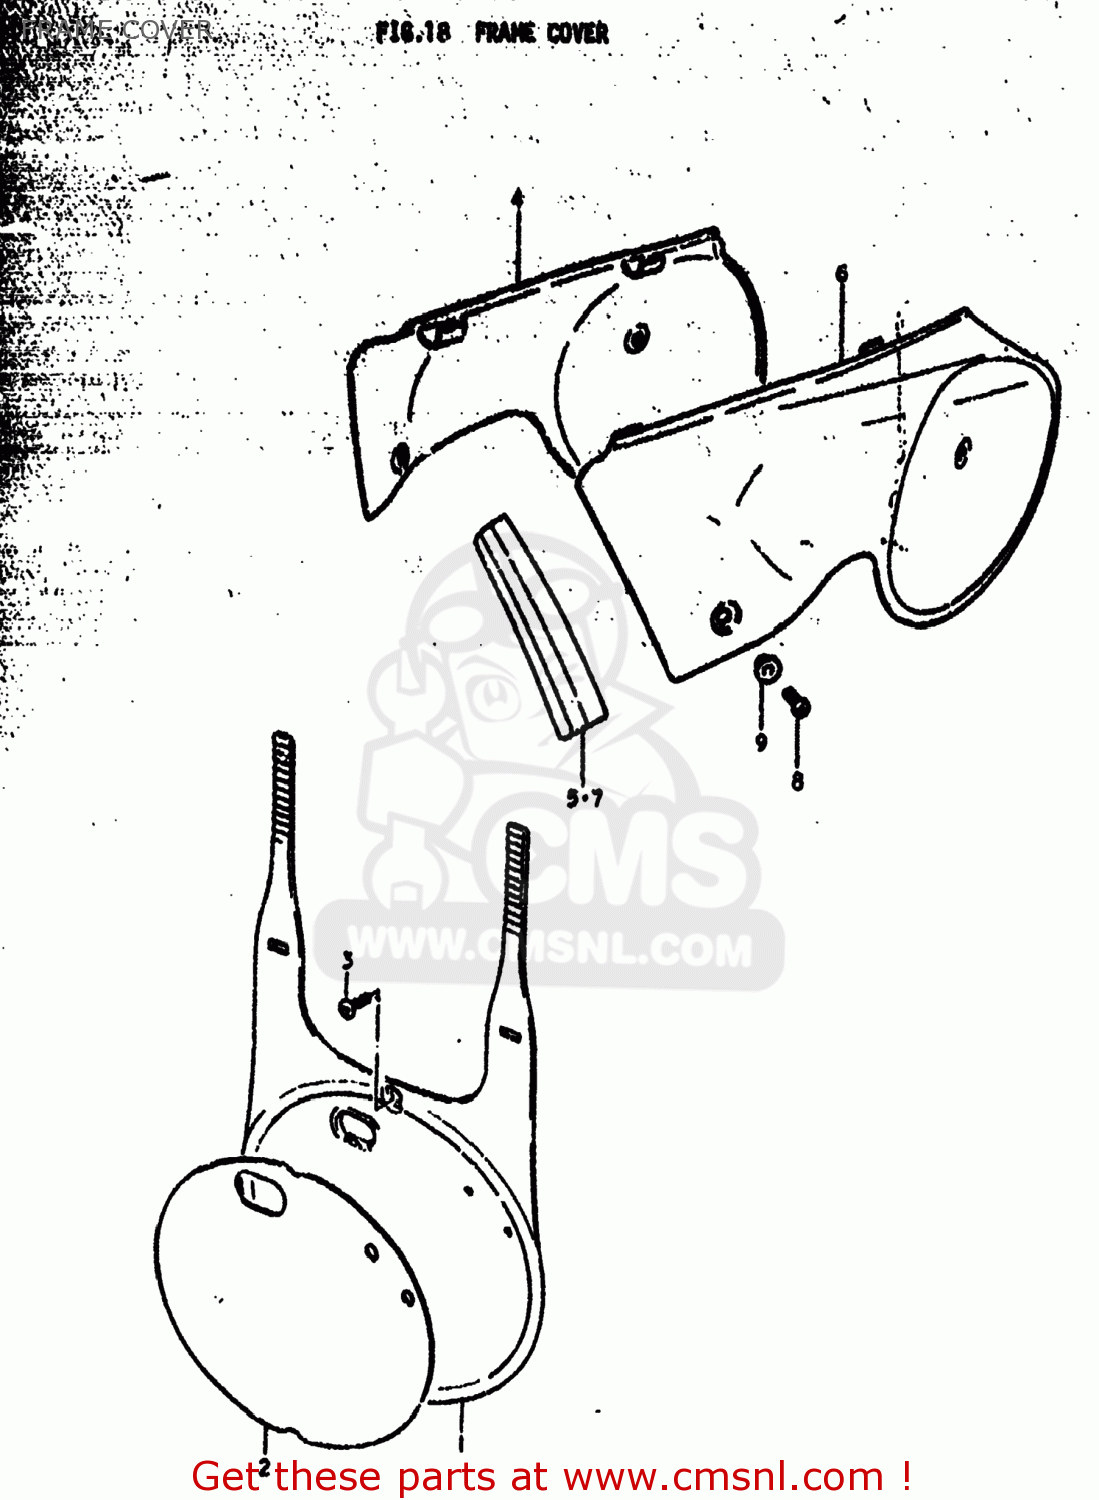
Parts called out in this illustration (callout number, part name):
1	PLATE,FR NUMBER
2	EMBLEM,FRONT NUMBER PLATE
3	(5X20) CROSS SCREW
4	COVER,FRAME,RIGHT
6	COVER,FRAME,LEFT
7	LABEL,FRAME COVER
8	SCREW 6X12
9	SPACER
